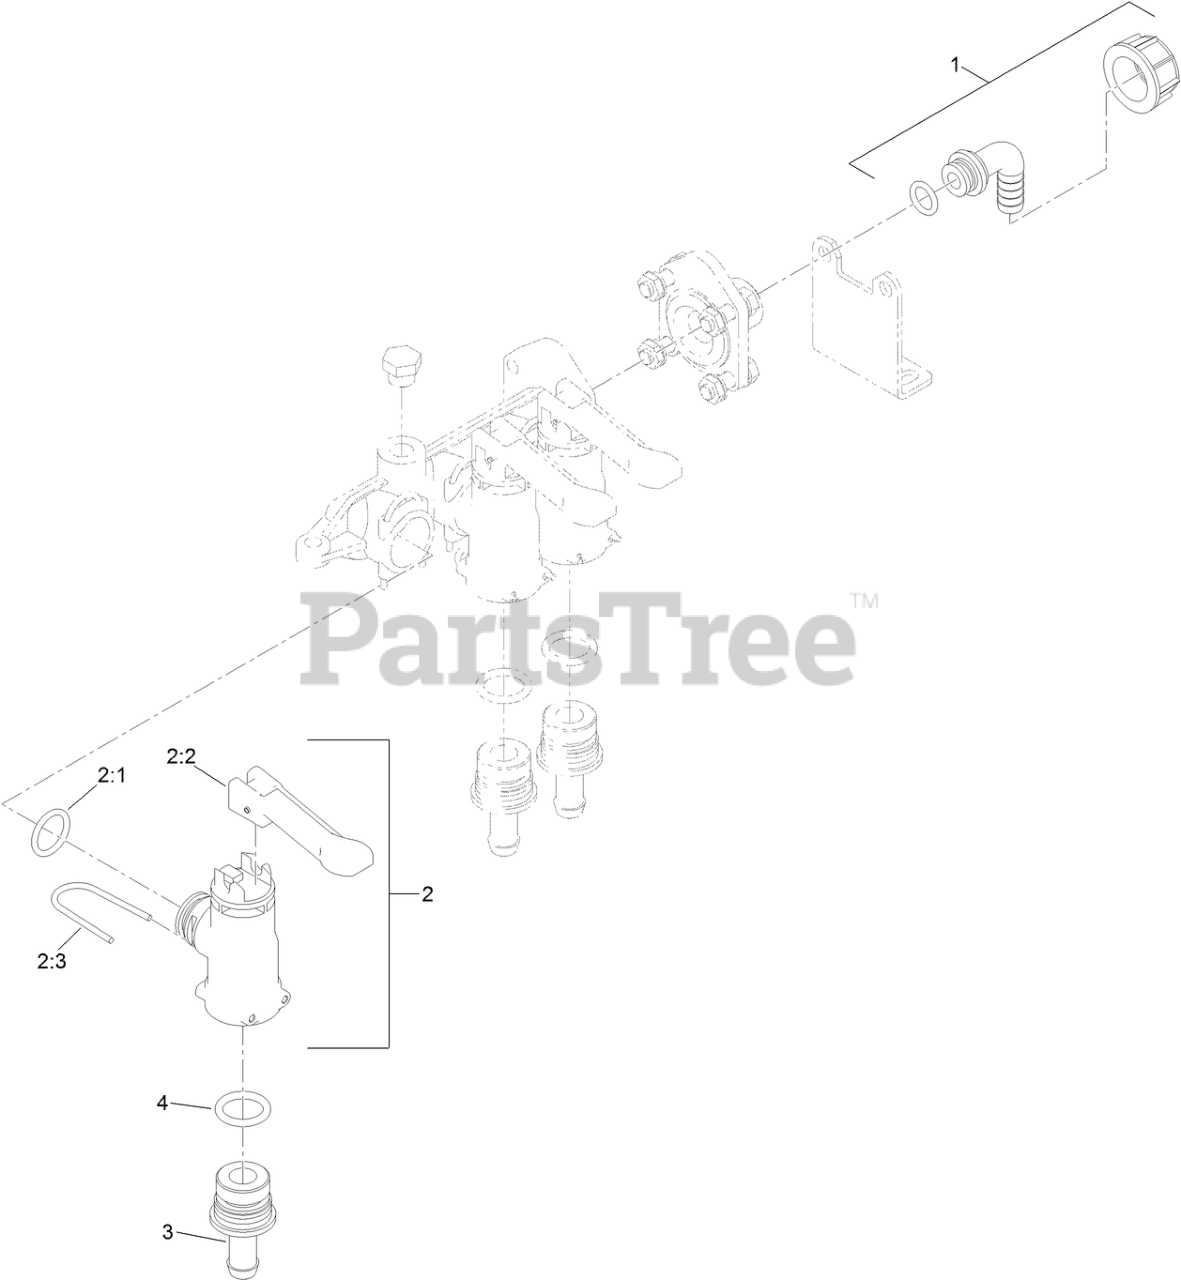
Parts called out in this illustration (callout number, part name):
1	FLYNUT ASSEMBLY
2	VALVE ASSEMBLY W/ O-RING
2:1	O-RING KIT, VALVE INLET
2:2	LEVER AND PIN ASSEMBLY
2:3	WIREFORM RETAINER KIT
3	HOSE BARB
4	O-RING KIT, VALVE OUTLET BARB
